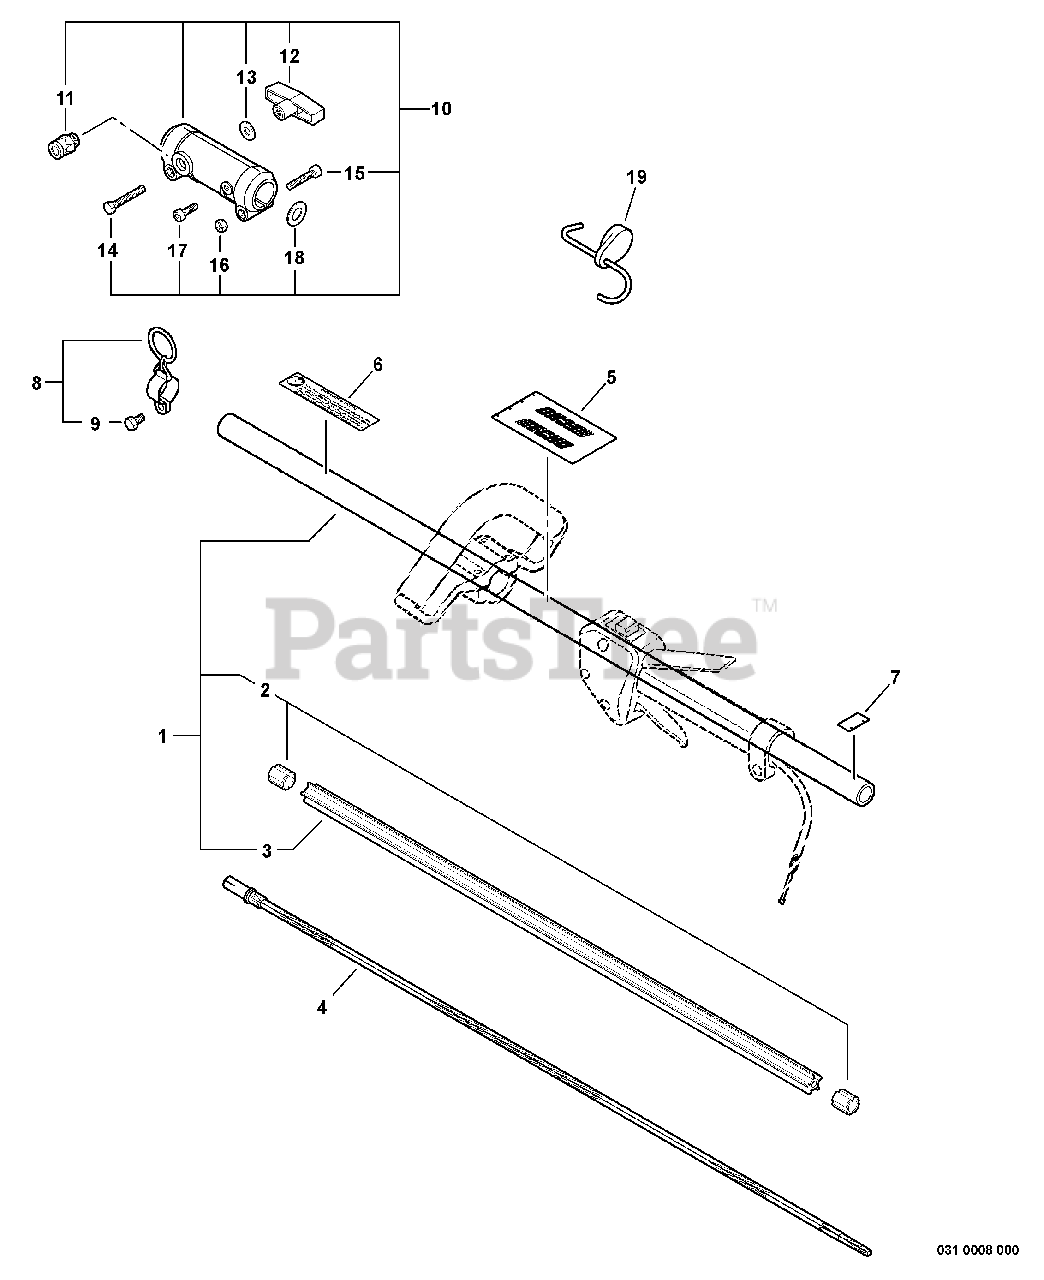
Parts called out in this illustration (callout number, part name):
1	MAIN PIPE ASSY
3	LINER - FLEXIBLE
4	DRIVESHAFT - FLEXIBLE
5	LABEL, HANDLE LOCATION
6	LABEL, CAUTION
7	LABEL - ALIGNMENT
8	HANGER SET, HARNESS
9	BOLT 5×12
10	COUPLER ASSY
11	LATCH ASSY
12	KNOB, FASTENER
13	WASHER 6.6×20×1.6
14	BOLT 6×40
15	BOLT 6×25
17	BOLT M6×10
18	WASHER 18 SPR STEEL
